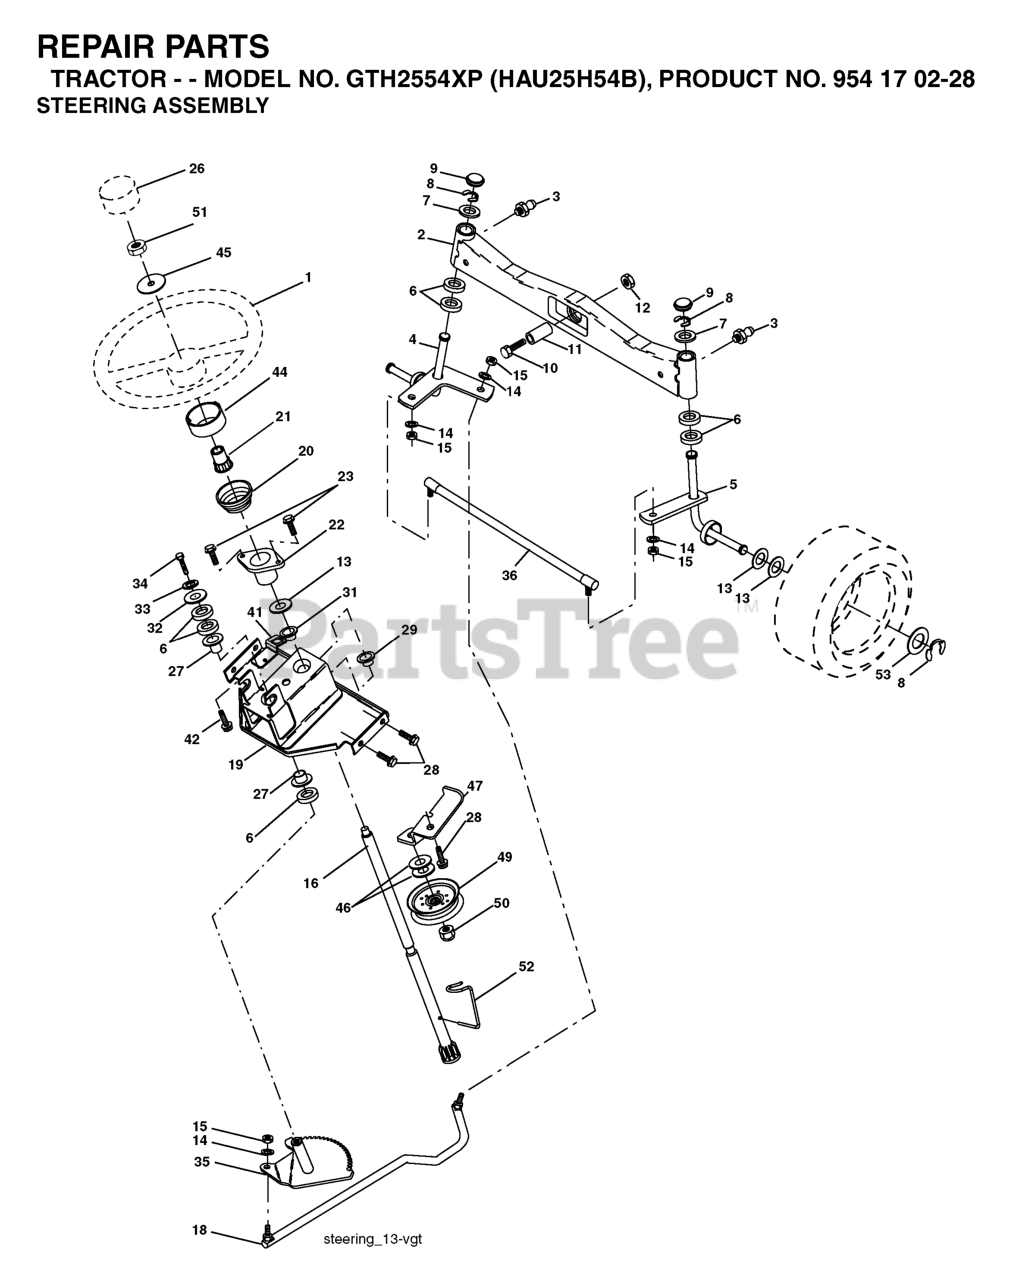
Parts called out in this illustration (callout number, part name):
1	STEERING WHEEL
2	AXLE.FRONT.CAST.MACHINE.W/ZERK
3	FITTING.GREASE.TAPERED
4	SPINDLE ASSY LH
5	SPINDLE ASM RH
6	THRUST WASHER
9	CAP.SPINDLE.BLACK
10	Bolt, Hex 5/8 -11 x 2 - 3/4 Gr. 5
11	TUBE, PIVOT AXLE
12	NUT-LOC,FLANGE LT
14	WASHER, LOCK 3/8
15	NUT CROWNLOCK 3/8-24
16	SHAFT ASM, STEERING
18	DRAGLINK.VGT.54"
19	SUPPORT ASM., STEERING VGT
20	BOOT, STEERING
21	STEERING WHEEL ADAPTOR
22	BUSHING, STRG. BLK
23	SCREW.TT.#10-32X.5.3/8.FLANGE
26	CAP.WHEEL.STEERING.GREY
27	BRNG T
28	SCREW, 3/8-16X3/4
29	BEARING-FLANGE GT
31	BUSHING.NYLINER.
33	WASHER.LOCK.HVY.HLCL.SPR.5/16
34	BOLT.FIN.HEX.5/16-18X3/4
35	GEAR.ASM.SECTOR.PITMAN
36	ROD.TIE.NON-ADJUSTABLE
41	BRACKET INTERLOCK
42	Screw 5/16-18 x 1/2 Hex, Self Tapping 5/16-18 x 1/2
44	EXTENSION STEERING PREMIUM
45	Washer 9/16 ID x 1 1/2 OD 11 Ga. Zin
47	BRKT.ASM.IDLER.STATIONERY
49	PULLEY.IDLER.FLAT.46.PR.DR.
50	NUT LOCK FLG 3/8-16 UNC
51	NUT.HEX.1/2-20
52	CLIP.STEERING
53	WASHER.HARDENED
